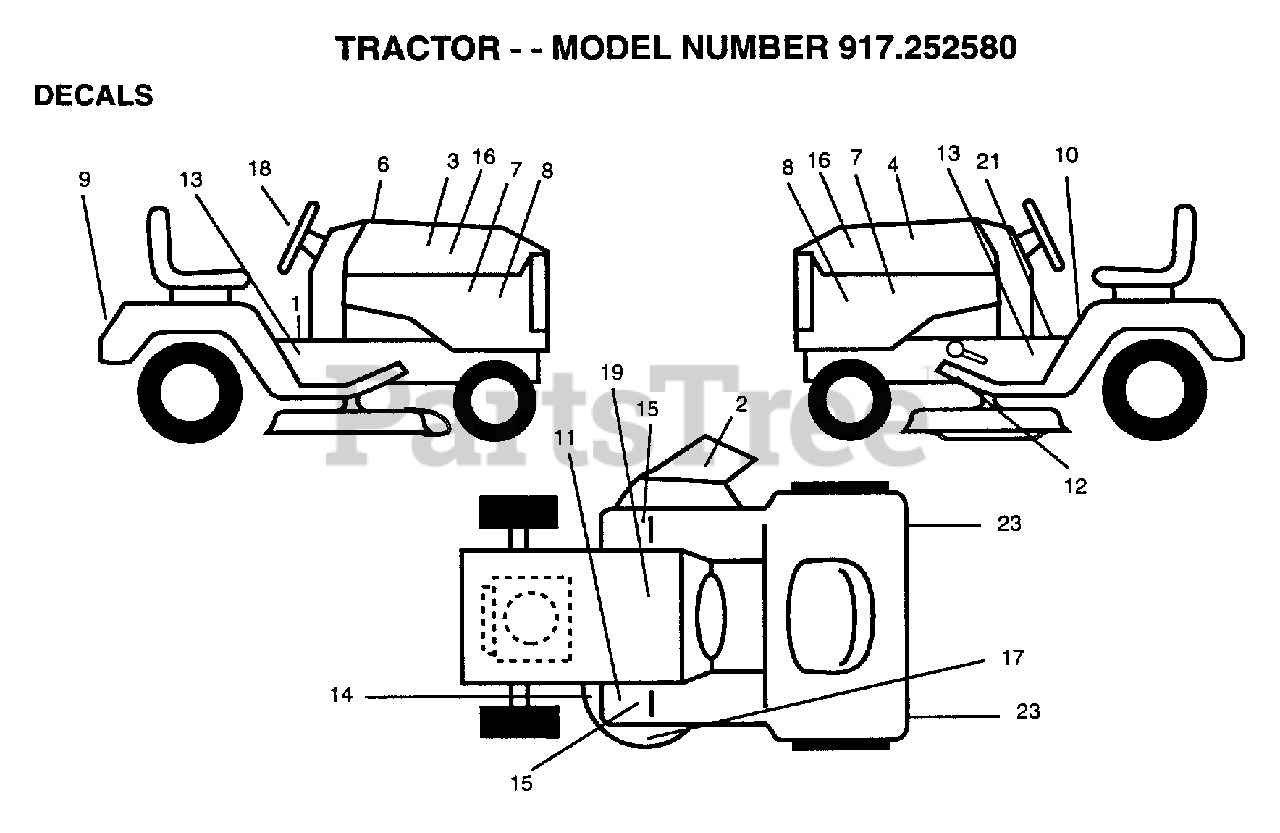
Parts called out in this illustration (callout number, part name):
2	MOWER DECAL
3	DECAL.HD.RH.CRFT.
4	DECAL.HD.LH.CRFT.
6	DECAL
7	DECAL.PANEL.SIDE
8	DECAL.SIDE.PANEL
12	DECAL.BELT-V.SCHM
13	CHASSIS DECAL
14	DECAL
16	DECAL.INS.HD.15.5
17	DECAL MWR QC SYS
18	DECAL.INS.STRG.WH
19	DECAL.BATTERY
21	DECAL BRAK PARK
23	REFLECTOR-TAIL YT
